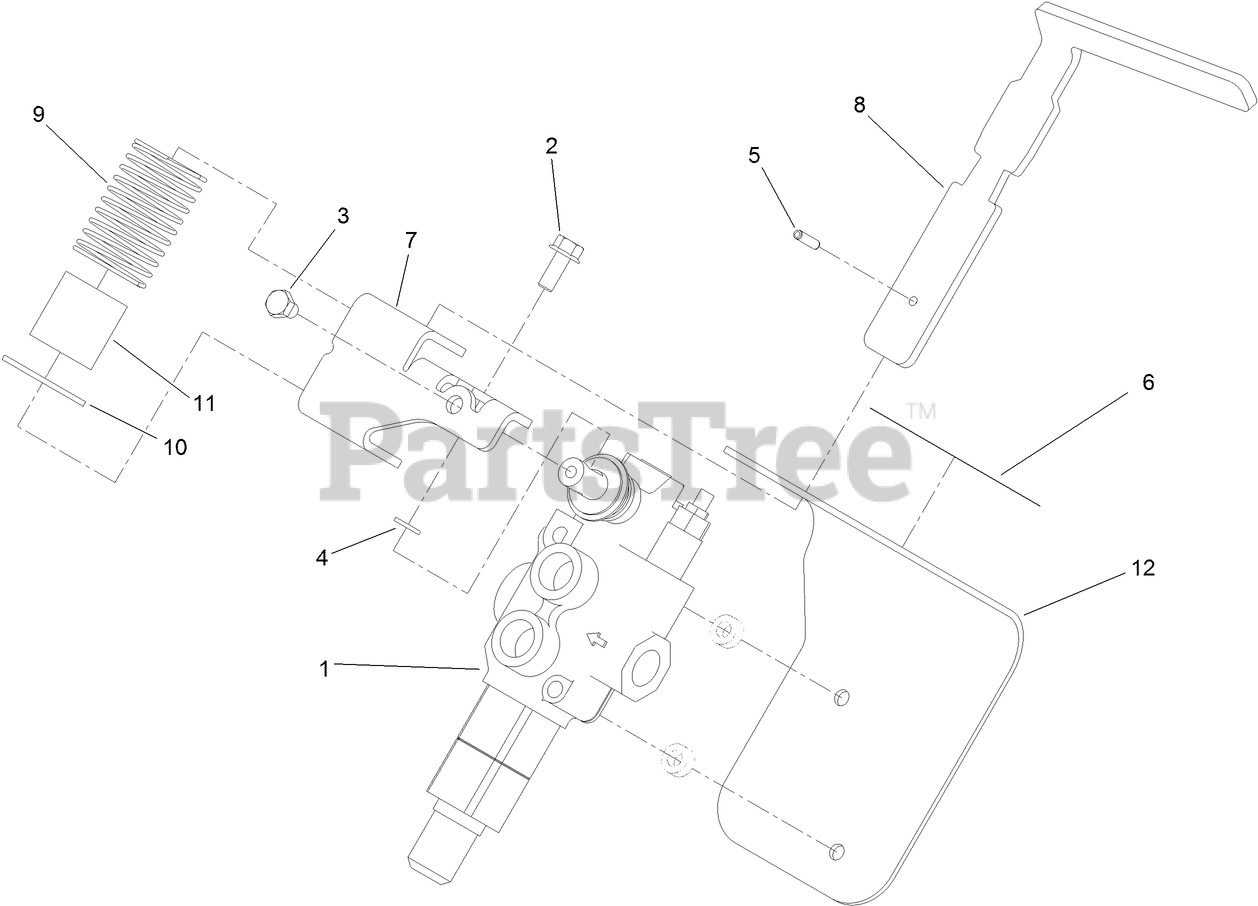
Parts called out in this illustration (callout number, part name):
1	VALVE-HYD, AUXILIARY
2	SCREW-HHF
3	SCREW-HH
4	WASHER-LOCK
5	PIN-SPRING
6	DECAL-AUXILIARY, CE
7	MOUNT-LEVER, AUXILIARY
8	HANDLE-LEVER, AUXILIARY
9	SPRING
10	RETAINER-SPRING, AUXILIARY
11	TUBE-SPRING
12	BRACKET-AUXILIARY
